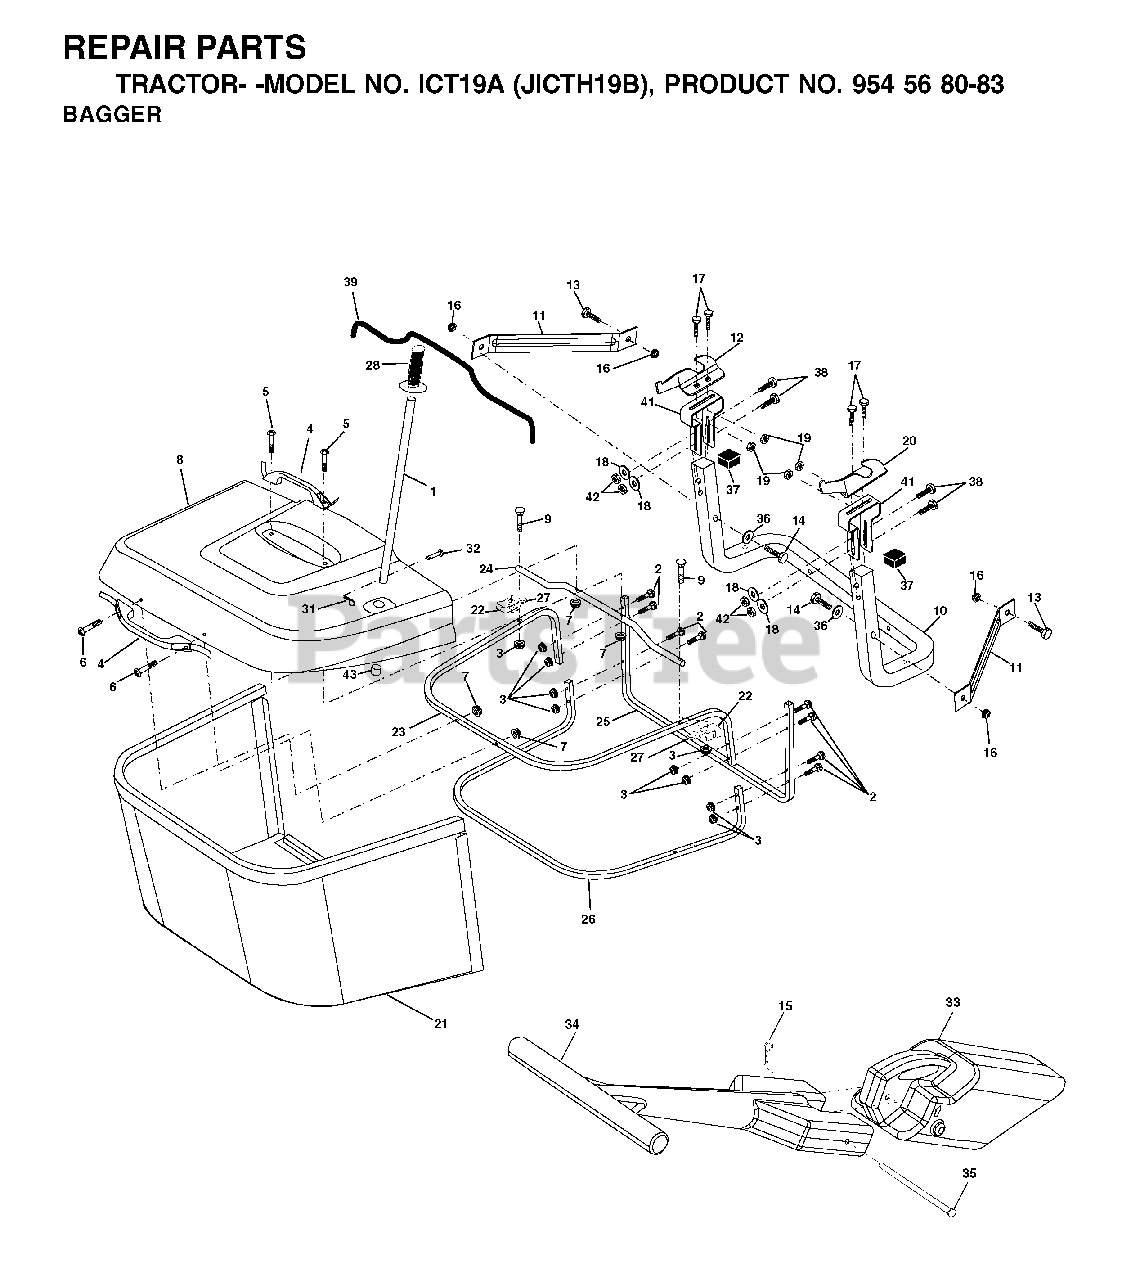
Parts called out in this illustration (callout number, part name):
1	TUBE HANDLE
3	NUT T
5	SCREW.PAN.HEAD
11	BRACKET
14	BOLT-HEX EAK
15	RETAINER-SPRNG RB
16	NUT LOCK FLG 3/8-16 UNC
17	BOLT
18	WASHER M
19	NUT LOCK HEX FLANGE 5/16-18
20	BRACKET
21	GRASS BAG
22	BRACKET
23	TUBE
24	TUBE
26	TUBE
28	GRIP.HANDLE.BLACK
31	RETAINER M
32	RIVET,DRILLED
33	MULCH PLUG, CTH150
35	PIN
36	WASHER
38	BOLT.5/16-18X2.5
41	BRKT, BAGGER
42	NUT.71038.31-18.HEX.NYLOCK
43	PLUG, TUBING END
